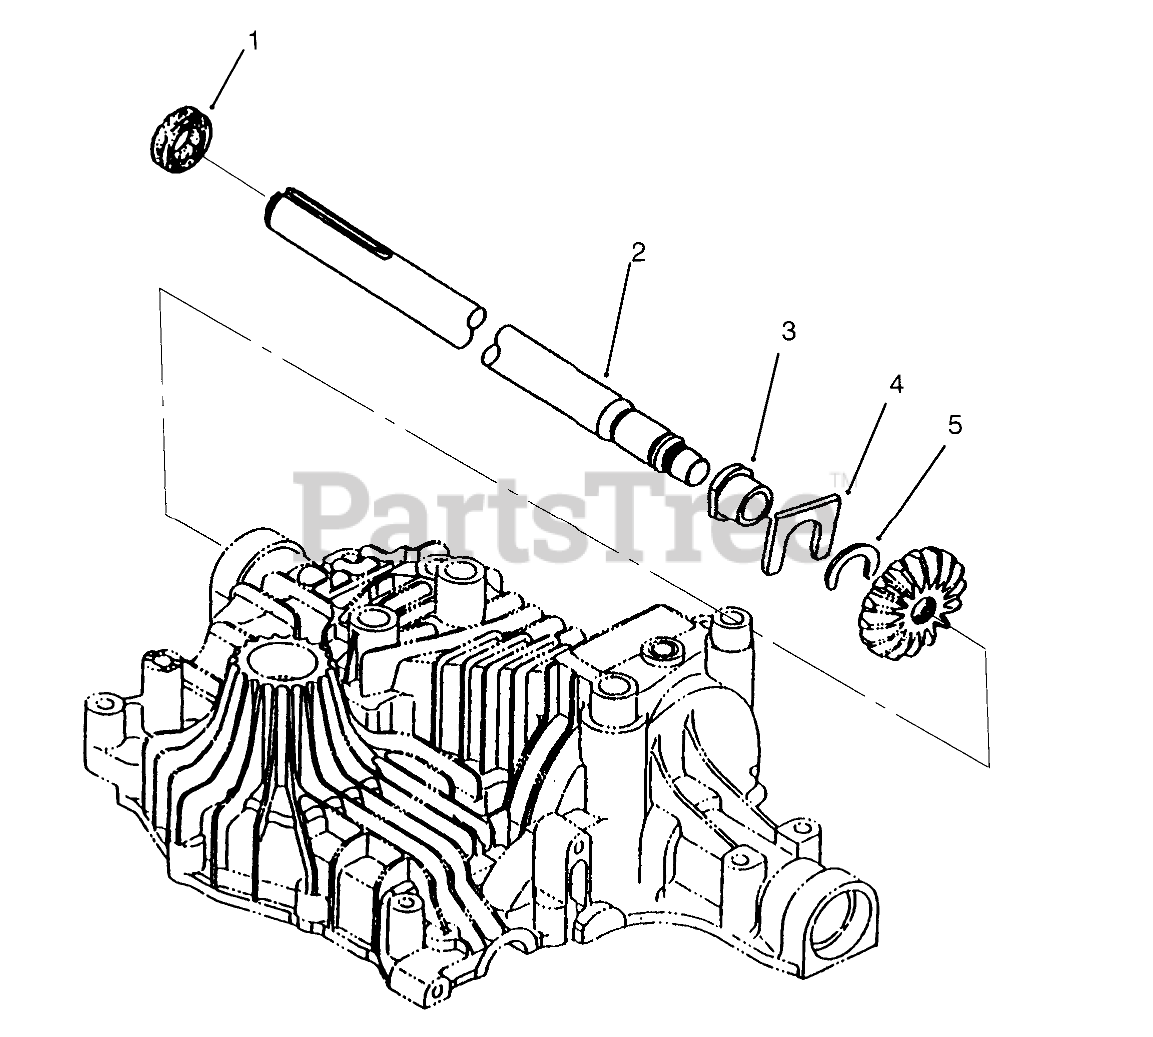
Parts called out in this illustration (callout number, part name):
1	Seal (Only On: 72043,72063,72103)
2	Shaft-Axle Right (Only On: 72043,72063,72103)
3	Bushing (Only On: 72043,72063,72103)
4	Washer-Thrust (Only On: 72043,72063,72103)
5	Ring (Only On: 72043,72063,72103)
